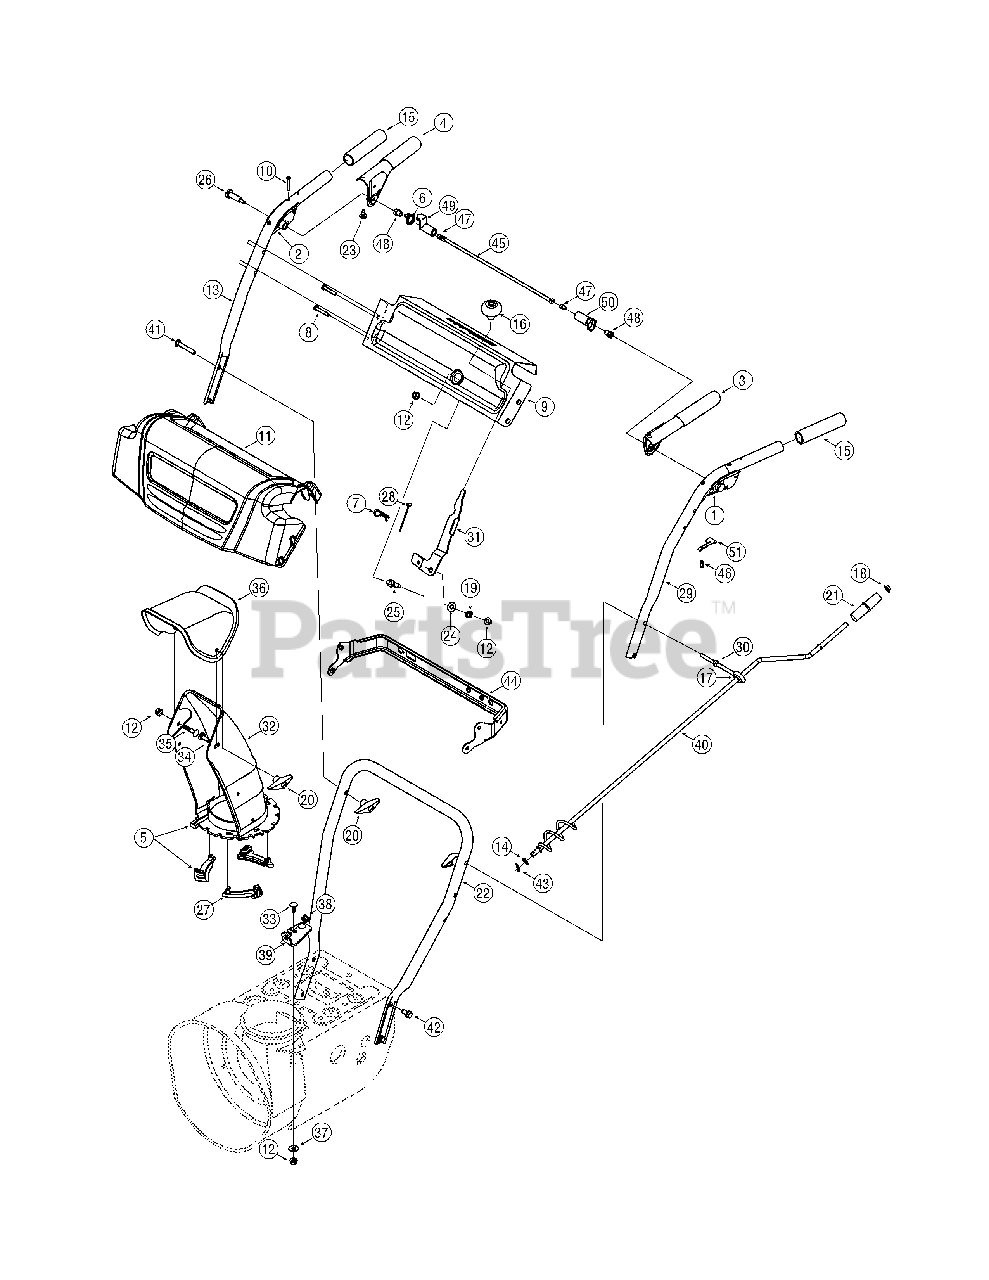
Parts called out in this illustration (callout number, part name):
1	Handle Assembly, Clutch Lock, LH
2	Handle Assembly, Clutch Lock, RH
3	Handle Ass’y, Engage, Red, LH
4	Handle Ass’y, Engage, Red, RH
5	Chute, Lower (Incl. Ref. # 27, Qty. 3)
6	Spring, Torsion, .8156 ID x .3038
7	Click Pin
8	Screw, 1/4-20 x 1.625
9	Panel, Handle, (no cutout)
10	Screw, Machine, #10-24, 1.375
11	Handle Panel Cover
12	Nut, Flange Lock, 5/16-18, Nylon
13	Handle, Upper, RH
14	Washer, Flat, .375 x .738 x .063
15	Grip, 1.0 ID x 5.0
16	Knob, Shift, Black
17	Grommet, .44 ID x .94 OD x .50
18	Cap, Push, 3/8 Rod
19	Spring, .39 x .60 x .88
20	Knob, 5/16-18, Black
21	Crank Knob, 1.0 Dia. x 3.2, Black
22	Handle, Lower
23	Bumper, Rubber, .62 OD x .22
24	Washer, Flat, .385 x .870 x .092
25	Bolt, Shoulder, 5/16-18 x 0.905
26	Screw, Shoulder, .43 x 1.3, 1/4-20
27	Chute, Flange Keeper
28	Cable, Speed Selector
29	Handle, Upper, LH
30	Eye Bolt, Chute Crank
31	Shift Lever
32	Chute, Lower, 5.0 Dia.
33	Bolt, Carriage, 5/16-18, 1.0
34	Bolt, Carriage, 5/16-18, 1.0
35	Bolt, Carriage, 5/16-18, .750
36	Chute, Upper, w/ Label
37	Washer, .349 x .879 x .063
38	Bushing, Plastic, .380
39	Bracket, Chute Crank
40	Crank Assembly, Chute
41	Screw, Carriage, 5/16-18, 2.25
42	Screw, 5/16-18, 2.25, Gr5
43	Pin, Cotter, .072 x 1.13
44	Bracket, Panel
45	Rod, Pivot
46	Screw., #8-16 x .50
47	Screw., 1/4-20 x .50
48	Nut, Hex, 1/4-20
49	Plate, Lock
50	Cam, Clutch Lock
51	Sping, Clutch Lock
